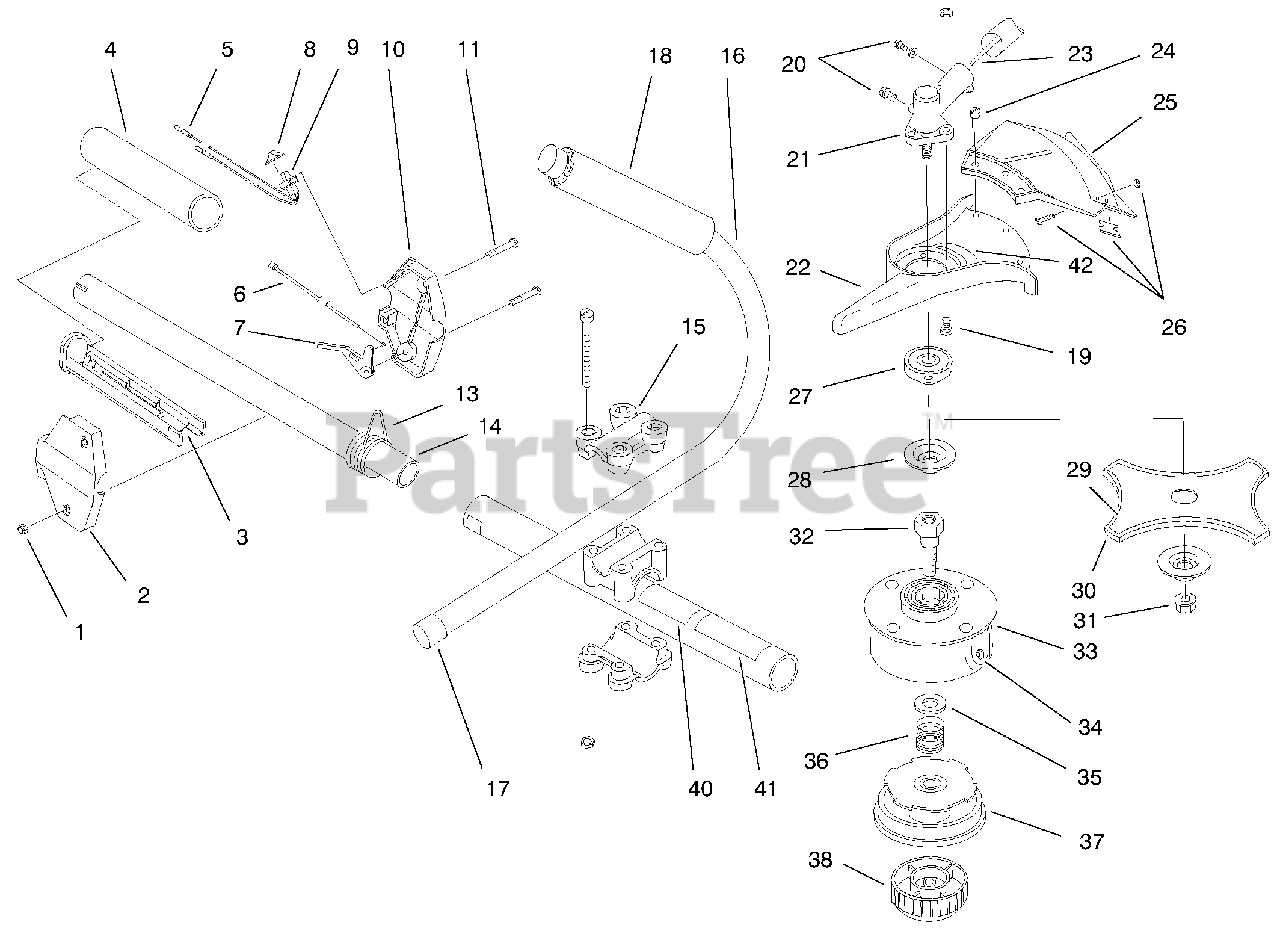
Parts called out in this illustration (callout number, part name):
25	Guard and Blade Asm.
26	Blade Asm.
27	Blade Driver
28	Blade Retaining Washer
29	Blade Cover
30	Blade (Incl. Ref. #29)
31	Lock Nut
32	Spool Shaft
33	Outer Spool & Eyelet Asm.
35	Retainer
37	Inner Reel
38	Bump Head Knob Asm.
40	Decal-Safety Symbols
41	Decal-Brushcutter Symbol
42	Decal-Warning
